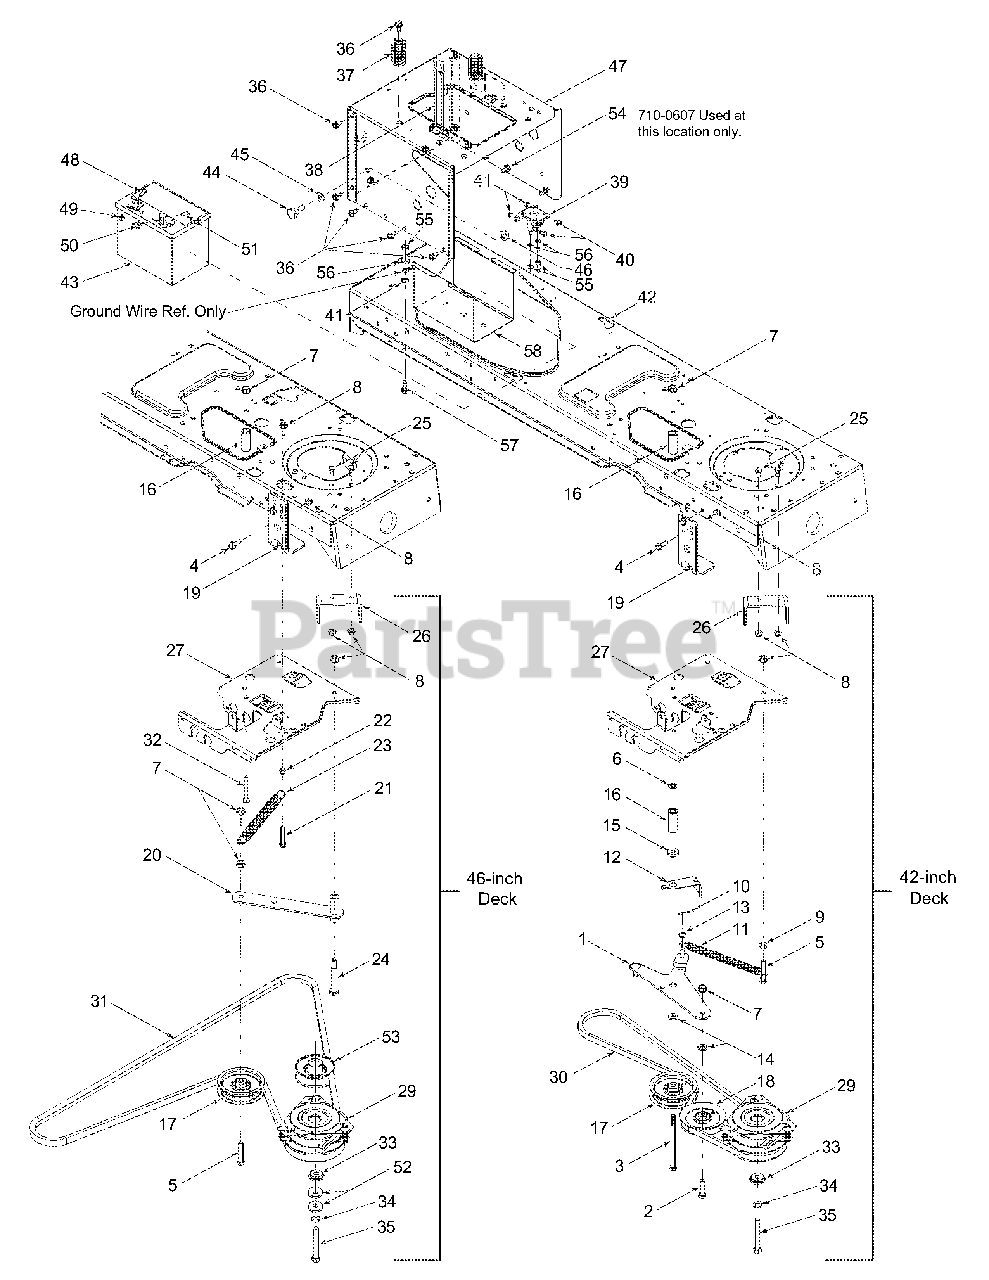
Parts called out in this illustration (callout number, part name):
3	Hex Cap Screw, 3/8-16 x 5.5
4	Hex Head Washer Screw, 5/16-18 x .875
5	Hex Cap Screw, 3/8-16 x 2.0
6	Push Nut, 3/8
7	Flange Lock Nut, 3/8-16
8	Flange Lock Nut, 5/16-18
9	Hex Nut, 3/8-16
10	Cotter Pin, 1/8 x 1.25
11	Extension Spring, .62 x 6.12
12	Belt Guard
13	Flat Washer, .385 x .62 x .063
14	Flat Washer, .407 x .812 x .135
15	Shoulder Spacer, .380
16	Spacer, 3/8 x 1.54
17	Idler Pulley, 3.5
18	Idler Pulley, 4.0
22	Hex Nut, 5/16-18
23	Extension Spring, .62 x 5.62
24	Shoulder Screw, 1/2 x 2.5
25	Hex Cap Screw, 5/16-18 x .625
30	PTO Belt (Models w/ 42-inch deck)
31	PTO Belt (Models w/ 46-inch deck)
32	Hex Cap Screw, 3/8-16 x 2.5
33	Shoulder Spacer, 1.38 x .445 x .36
34	Lock Washer, 7/16
35	Hex Cap Screw, 7/16-20 x 3.25 (Grade 5)
36	Self Tapping Screw, 5/16-18 x .625
37	Compression Spring, 1.28 x 3.125
38	Battery Strap
39	Solenoid, 12-Volt, 100 Amp
40	Self Tapping Screw, 1/4-20 x .5
41	Lock Washer, 1/4
44	Shoulder Screw, .625 x .5, 7/16-20
45	Bell Washer, .45 x 1.0 x .062
46	Flange Lock Nut, 7/16-20
49	Hex Sems Nut, 1/4-20
50	Wing Nut, 1/4-20
51	Shoulder Screw, 1/4-20, .25 x .15
52	Flat Washer, .4375 x 1.25 x .180
53	Engine Pulley
54	Self-tapping Screw, 5/16-18 x .5
55	Hex Nut, 1/4-20
56	Lock Washer, 1/4
57	Self-tapping Screw, 1/4-20 x .75
